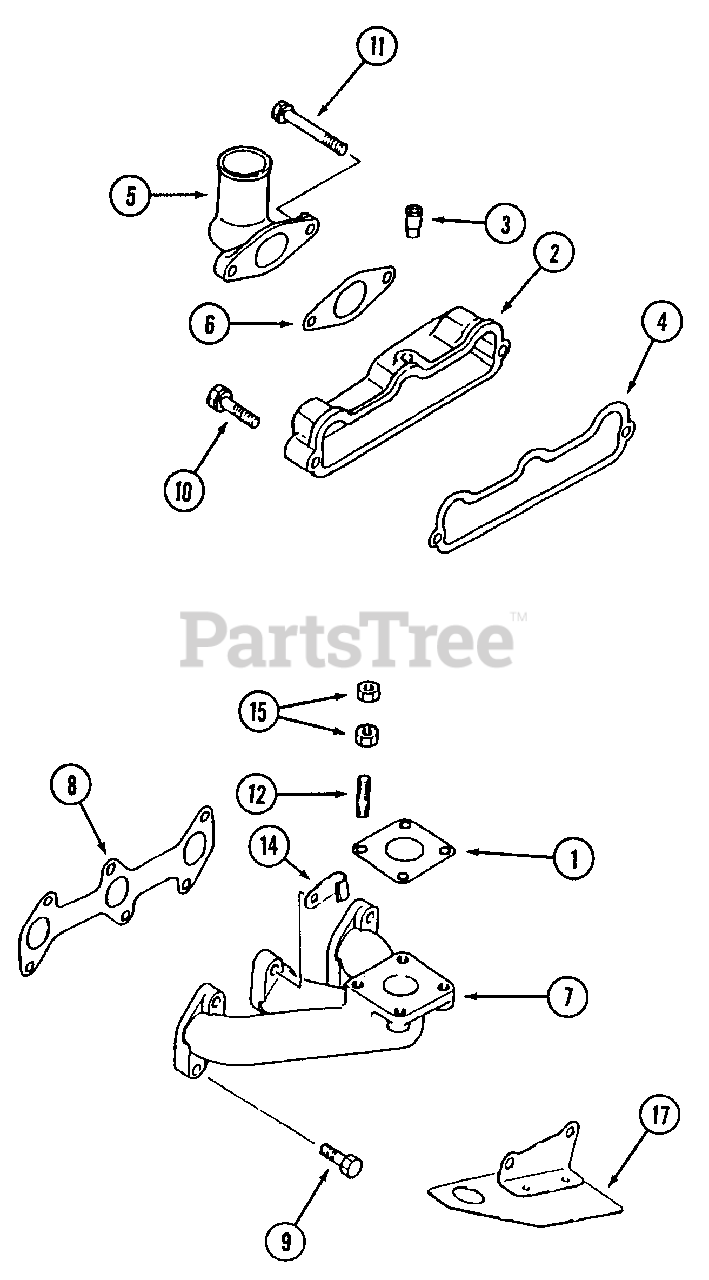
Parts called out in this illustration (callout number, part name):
2	Intake Cover Ass'y.
3	Pipe
4	Gasket, Intake Manifold
5	Pipe, Inlet
6	Gasket, Inlet Pipe
7	Manifold, Exhaust
8	Gasket, Exhaust Manifold
10	Bolt,
11	Bolt,
12	Stud
14	Clamp, Tachometer Cable
17	Cover Starter
